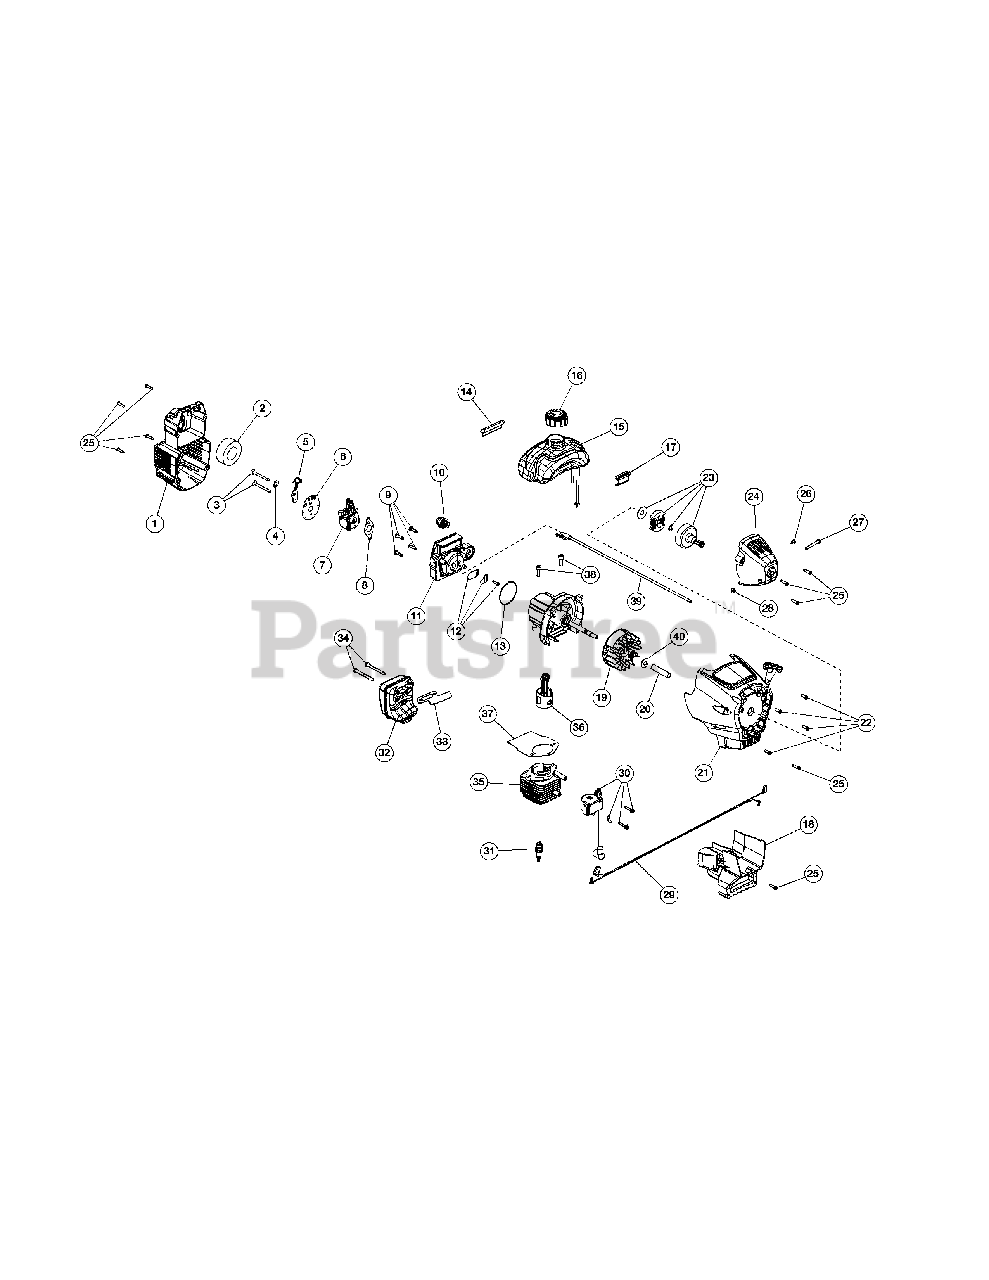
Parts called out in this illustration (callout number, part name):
1	Air Cleaner Cover Assembly (Incl. 2 & 25)
2	Air Cleaner Filter
3	Carburetor Mounting Screw Assembly
4	Wavey Washer
5	Choke Lever Assembly
6	Choke Plate Assembly (Incl. 5)
7	Carburetor Assembly (Incl. 8)
8	Carburetor Gasket
9	Carb Mount Screw
10	Primer & Hose Assembly
11	Carb Mount Assembly (Incl. 9, 12 & 13)
12	Reed Assembly
13	O-Ring
14	Rear Mounting Pad
15	Fuel Tank Assembly (Incl. 16)
16	Fuel Cap Assembly
17	Front Mounting Pad
18	Shroud Extension & Stand (Incl. 25)
19	Flywheel Assembly
21	Starter Housing Assembly (Incl. 22 & 25)
22	Housing Screw
23	Clutch Rotor Assembly
24	Clutch Cover Assembly (Incl. 25-28)
25	Cover Screw
26	Anti-Rotation Screw
27	Clamping Screw
28	Clamping Nut
29	Wire Leads and Sleeve
30	Module Assembly
31	Spark Plug
32	Muffler Assembly
33	Exhaust Gasket
34	Muffler Mounting Bolts
35	Cylinder Assembly (Incl. 37 & 38)
36	Piston and Rod Assembly
37	Cylinder Gasket
38	Cylinder Bolt
39	Throttle Cable
40	Washer
